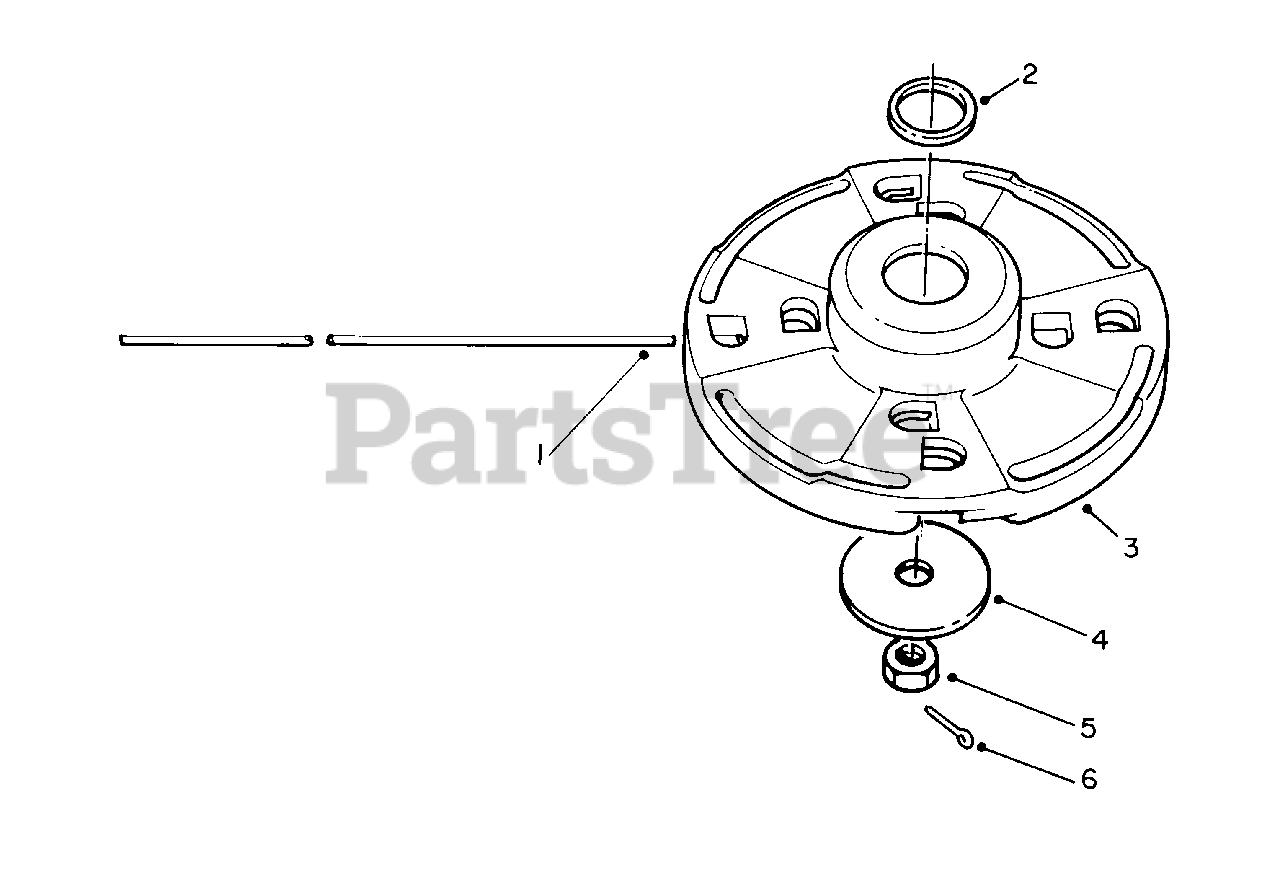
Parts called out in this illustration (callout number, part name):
1	Line-Cutting .105 Dia. (100 Pcs. Optional)
3	Head Assembly (Incl. Ref. #2)
4	Washer-Plate
5	Nut-Hex.
6	Pin-Cotter
